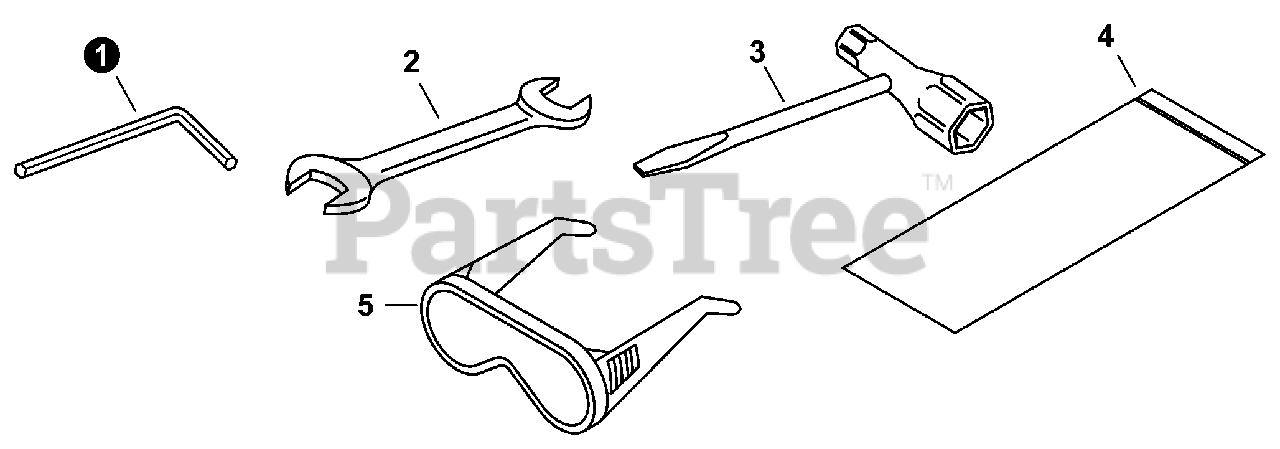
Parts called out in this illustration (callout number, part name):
1	WRENCH, ALLEN 4MM
2	SPANNER 8×10
3	T-WRENCH 17×19mm
4	BAG, TOOL
5	GLASSES, SAFETY
